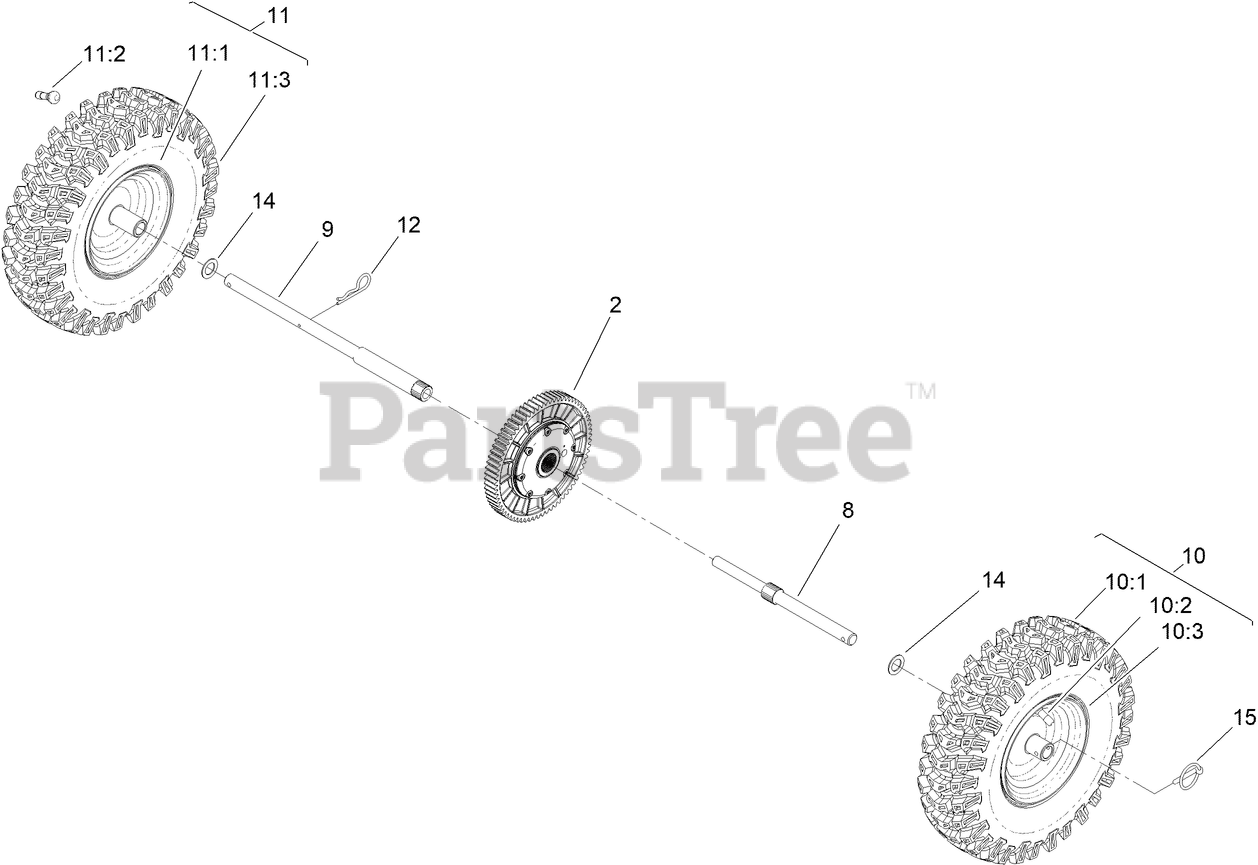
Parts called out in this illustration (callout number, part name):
2	TRANSMISSION-GT, DI200
8	AXLE-LT, CTS
9	AXLE-RT, CTS
10	LH WHEEL AND TIRE ASM
10:1	WHEEL (15X4 TIRE)
11	RH WHEEL AND TIRE ASM
11:1	WHEEL (15X4 TIRE)
12	PIN-HAIR
14	WASHER-THRUST
15	KLIK PIN ASM
